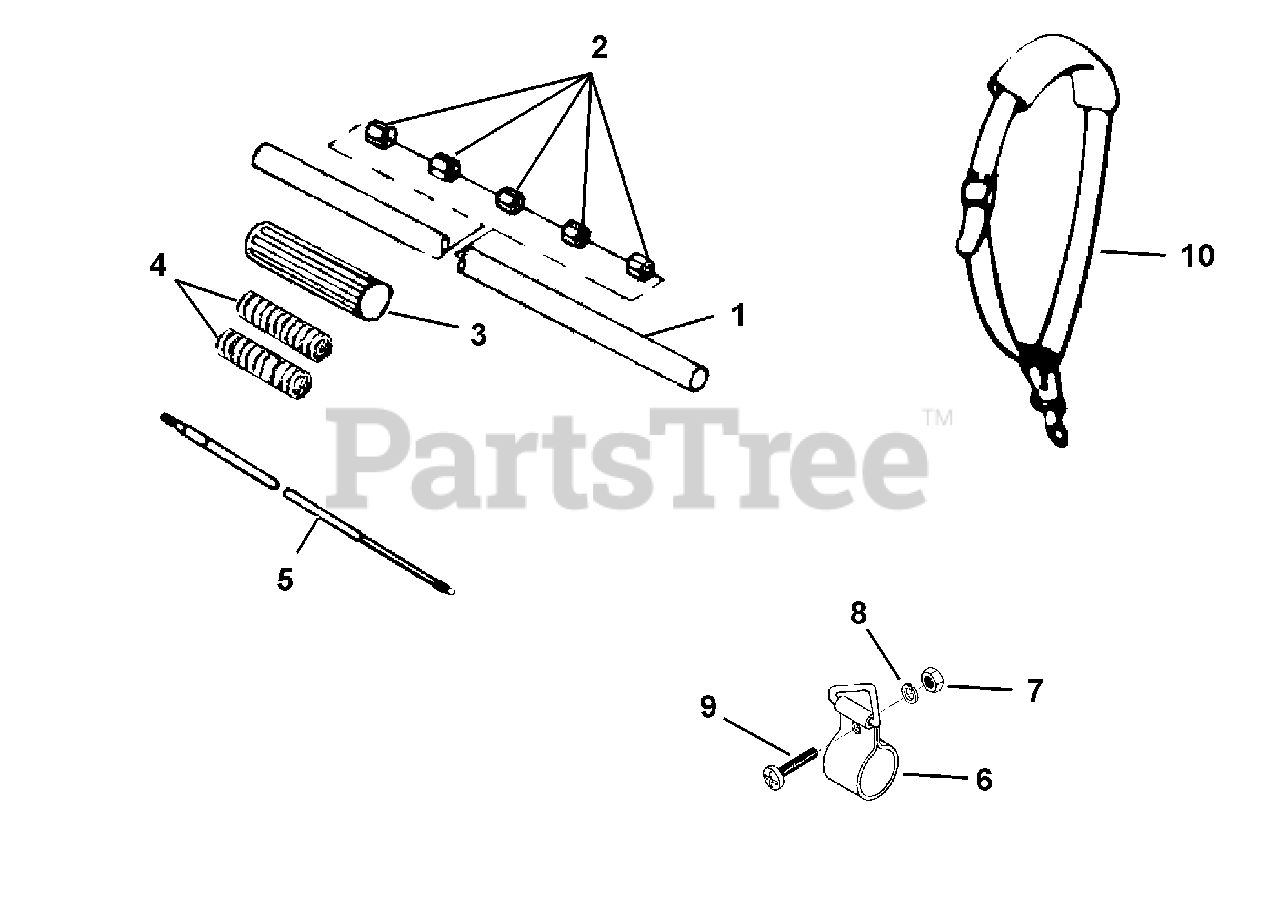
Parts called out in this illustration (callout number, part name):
1	Driveshaft Tube Assembly
5	Driveshaft
6	Hanger Assembly
7	Nut
